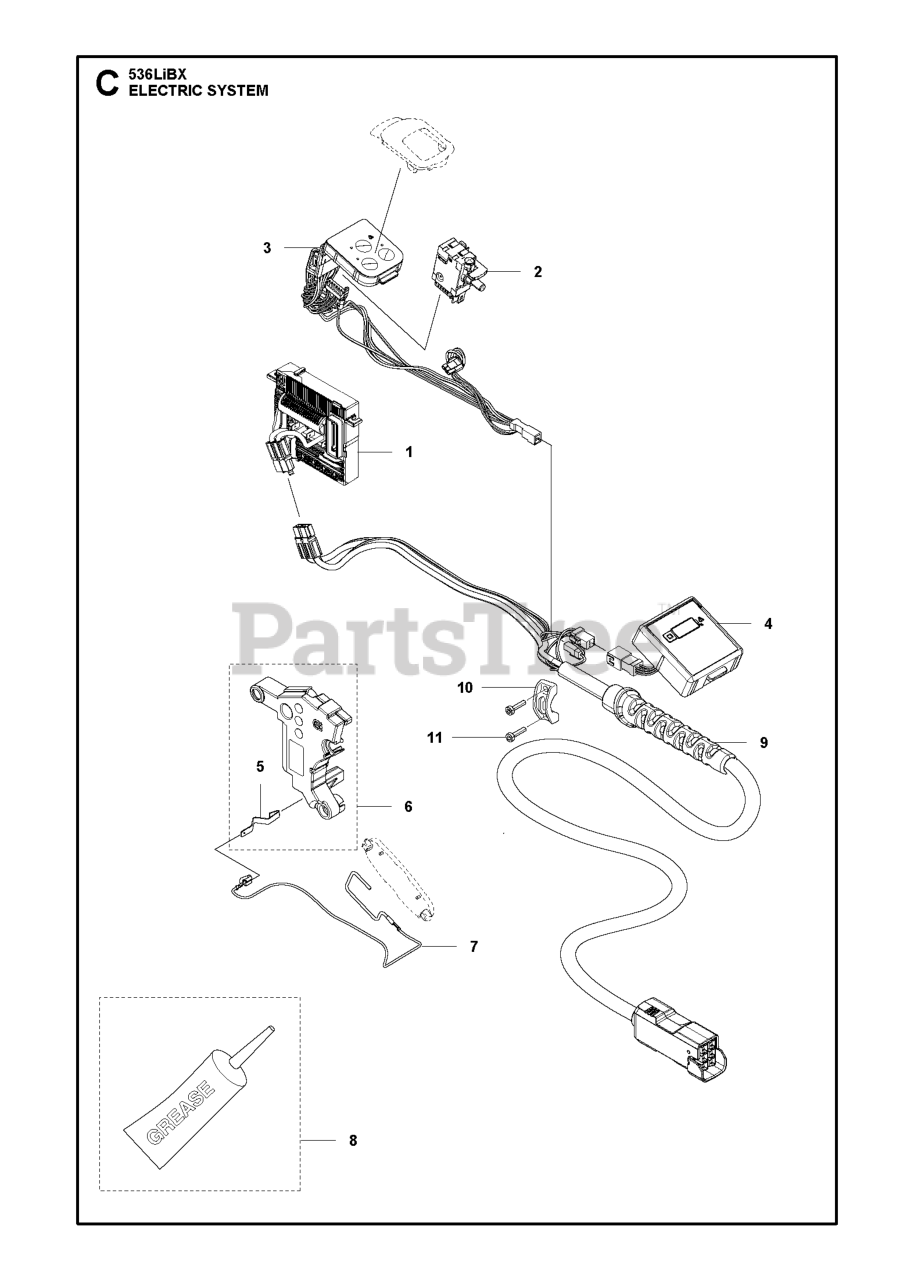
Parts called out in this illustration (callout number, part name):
1	CONTROL UNIT BLDC MID SPEC, GE
2	TRIGGER SWITCH
6	KIT COVER ELECTRONICS
7	WIRING ASSY
8	GREASE TUBE Q8 RUYSDAEL WR2
10	CABLE CLAMP
11	SCREW
